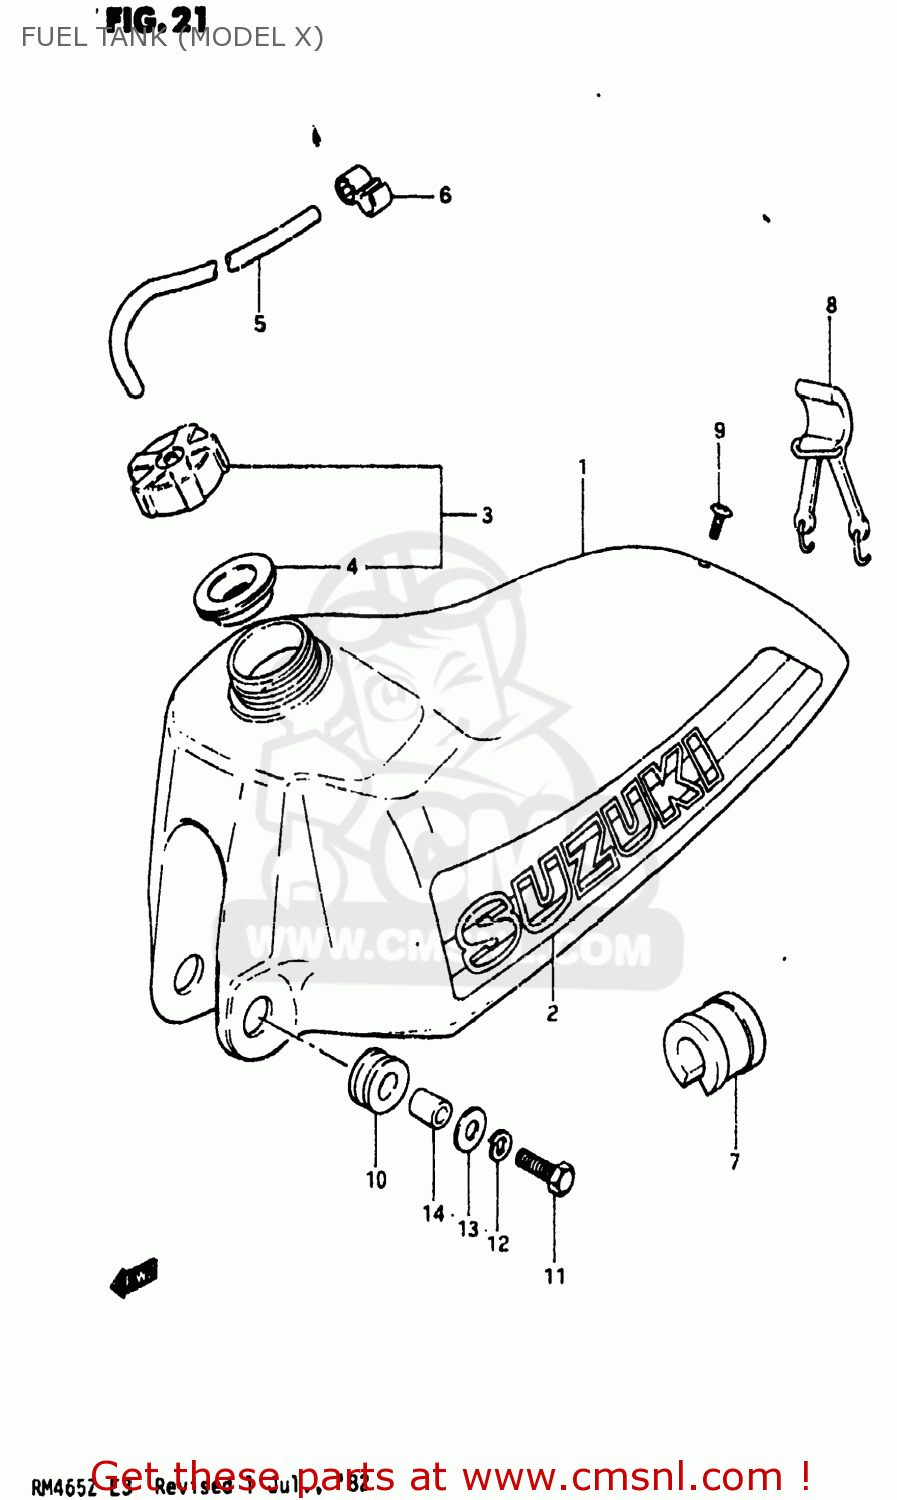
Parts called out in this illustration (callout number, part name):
1	TANK ASSEMBLY,FUEL
2	TAPE SET,FUEL TANK
3	CAP SET,FUEL TANK
4	GASKET,FUEL TANK CAP (NAS)
5	HOSE
6	CLAMP,BREATHER HOSE
7	CUSHION,FUEL TANK UPR
8	BAND,FUEL TANK,REAR
9	SCREW (6X15)
10	CUSHION
11	BOLT (8X30)
12	LOCK WASHER
13	WASHER (8.5X29X1.6)
14	SPACER (8.8X12X15.5)
